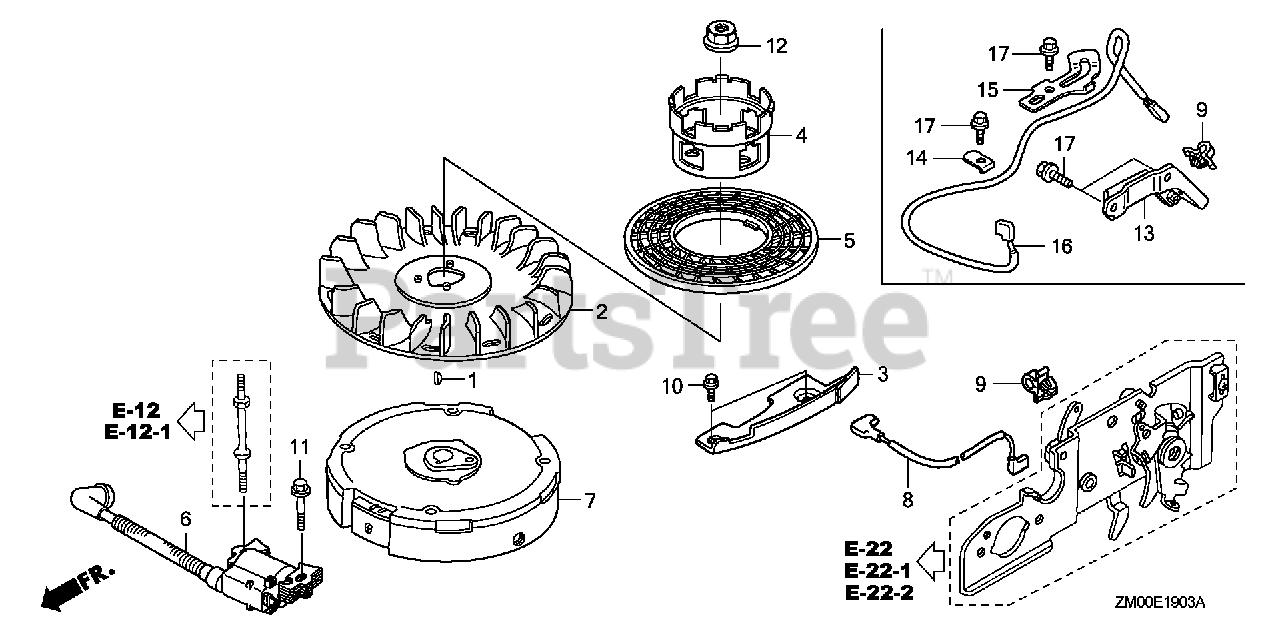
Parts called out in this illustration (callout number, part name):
1	KEY, SPECIAL WOODRUFF (25X18)
2	FAN, COOLING
3	PLATE, SIDE
4	PULLEY, STARTER
6	COIL ASSY., IGNITION (PHELON)
7	FLYWHEEL
8	WIRE, STOP SWITCH
9	HOLDER, WIRE (FASTEX)
9	CLIP, CABLE (A)
10	BOLT, FLANGE (6X12) (CT200)
11	BOLT, FLANGE (6X23)
12	NUT, SPECIAL (14MM)
